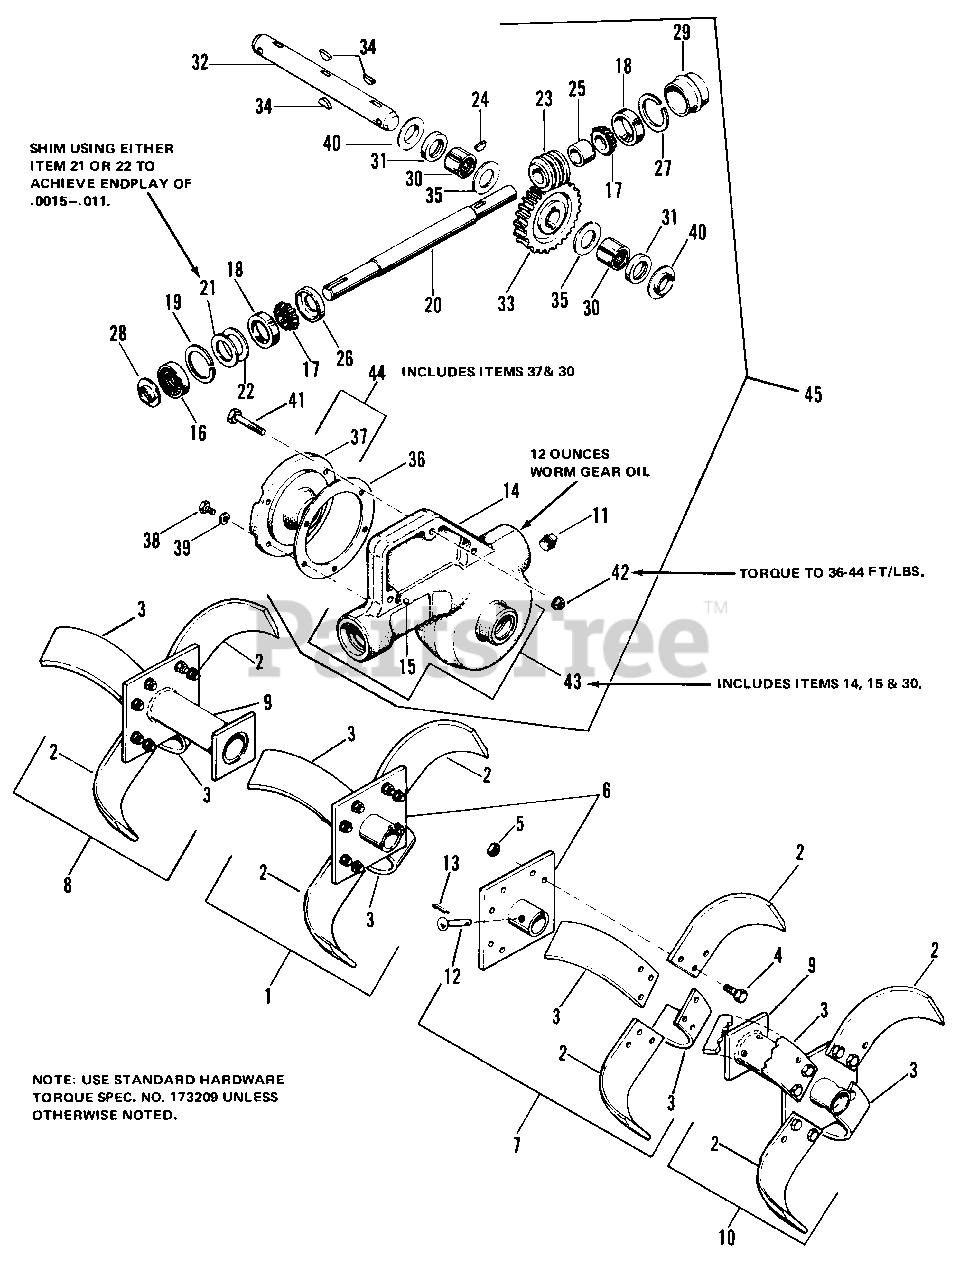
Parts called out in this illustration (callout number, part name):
1	BLADE ASSY, Inner Tine, L.H.
2	TINE BLADE, R.H.
3	TINE BLADE, L.H.
4	CAPSCREW, Hex Hd., 3/8-16 x 1
5	NUT, Hex, Full Lock, 3/8-16
6	PLATE ASSY, Inner Tine
7	BLADE ASSY, Inner Tine, R.H.
8	BLADE ASSY, Tine Ext., L.H.
9	PLATE ASSY, Tine, Outer
10	BLADE ASSY, Tine Ext., R.H.
11	PLUG, Pipe, Sq.Hd., 3/8
12	PIN
13	PIN, Cotter, 1/8-3/4
14	HOUSING, Worm Drive
17	CONE, Bearing
18	CUP, Bearing
19	RING, Retaining
20	SHAFT, Worm
21	RING, Backing
22	RING, Backing
23	WORM, R.H.
24	KEY, Hi-Pro, 3/16 x 7/8
27	RING, Retaining
29	CAP, Hub
30	BEARING, Needle
32	SHAFT, Worm Gear
33	GEAR, Worm
34	KEY, Woodruff, 1/4 x 3/4, No. 91
35	WASHER, Thrust
38	CAPSCREW, Hex Hd., 1/4-20 x 5/8
39	LOCKWASHER, Spring, 1/4
41	CAPSCREW, Hex Hd., 3/8-16 x 1-3/4
42	NUT, Flange, Hex, Whiz Lock, 3/8-16
43	HOUSING, BEARING & PLUG ASSY
45	WORM DRIVE ASSY
